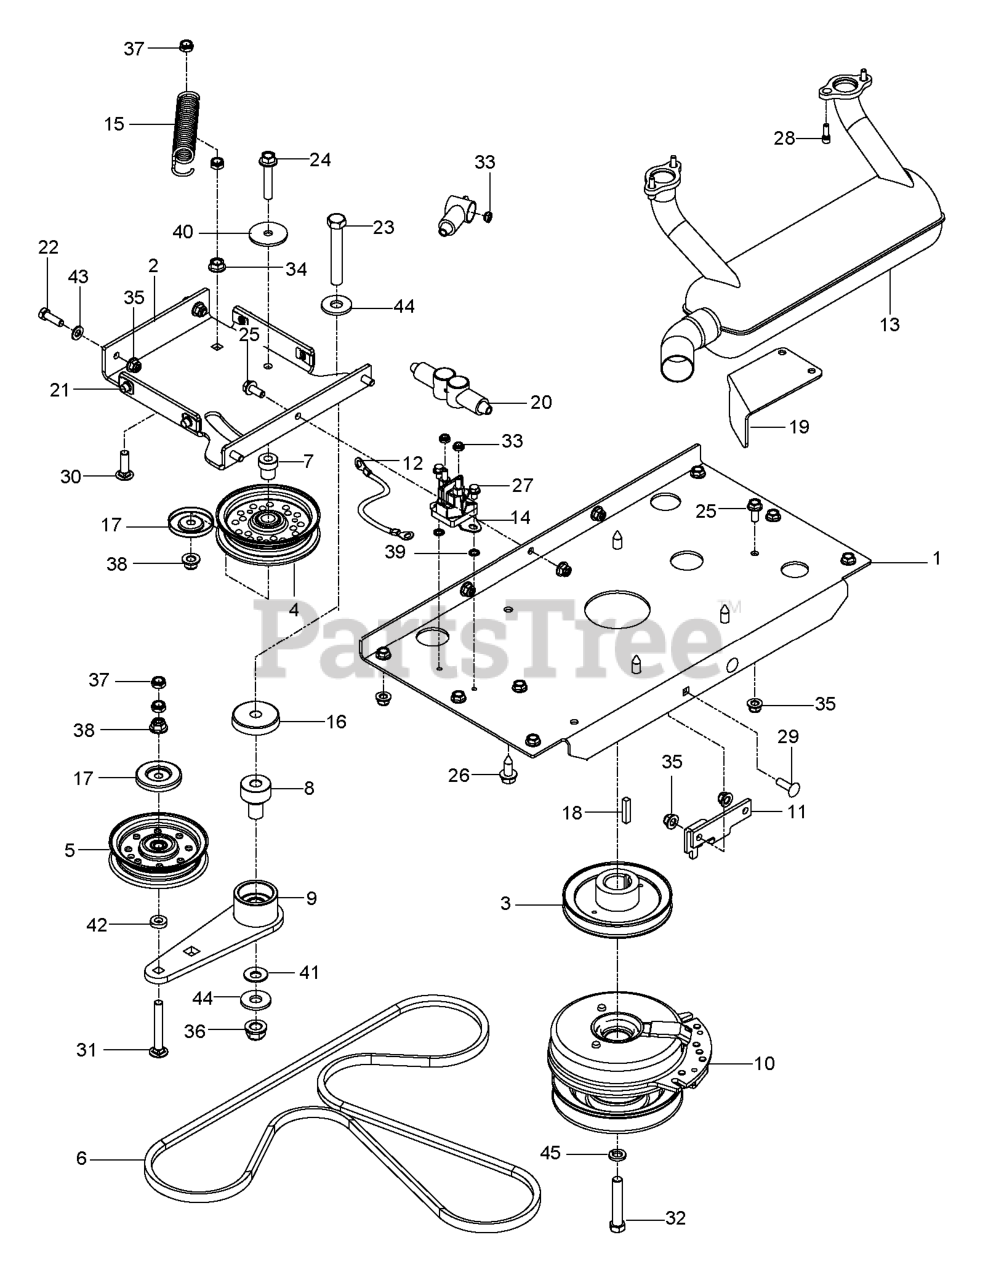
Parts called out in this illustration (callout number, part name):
1	PLATE, ENGINE, BLK
2	PLATE, IDLER, BLK
3	PULLEY, V, 1.125 BORE
4	IDLER PULLEY
5	FLAT IDLER PULLEY
6	BELT, HYDRO, 3400
7	PIVOT, IDLER
8	PIVOT, BEARING
9	ARM, IDLER, STEEL, W/BGS
10	CLUTCH 200 FT LB
11	STOP, CLUTCH, BLACK
12	CABLE POSITIVE
13	MUFFLER, B&S CYCLONIC
15	SPRING, PUMP
16	SHIELD, DUST
17	DUST SHIELD
18	KEY, 1/4 SQ X 1 1/4
19	SHIELD MUFFLER
21	U-CLIP 5/16-18 NUT RETAINER
22	HCS 5/16C X 1
23	HCS 1/2C X 3 1/4
24	HHFS 3/8-16 X 2.0 GD 5
25	HHFS 5/16-18 X 3/4
26	HHFS 3/8-16 X 1.0 THD FORMING
27	HWST 1/4C X 3/8
28	SCREW.SOCKET.HEAD.5/16-18
29	RHSSNB 5/16C X 1.0
30	RHSNB 3/8-16 X 1-1/4
31	RHSNB 3/8-16 X 2.75
32	BOLT 7/16F X 2 1/2
33	JAM NUT 1/4C (2 2 PW01)
34	NUT 3/8C WHIZ
35	5/16-18 NYLOC FLANGE NUT
36	NUT, 1/2-13 HEX FLG NYLOC ZD
37	NUT HEX 3/8-16 NYLON, THIN
38	NUT 3/8-16 HEX FLG NYLOC ZD
39	WASHER 1/4 INT TOOTH
40	WASHER, 3/8 SPEC
41	CONTACT BELLSPR 1/2
42	WASHER 3/8 X 3/4 X .187 TK
43	FLAT WASHER 5/16 SAE
44	WASH USS FLAT 1/2
45	WASHER 7/16 LOCK
